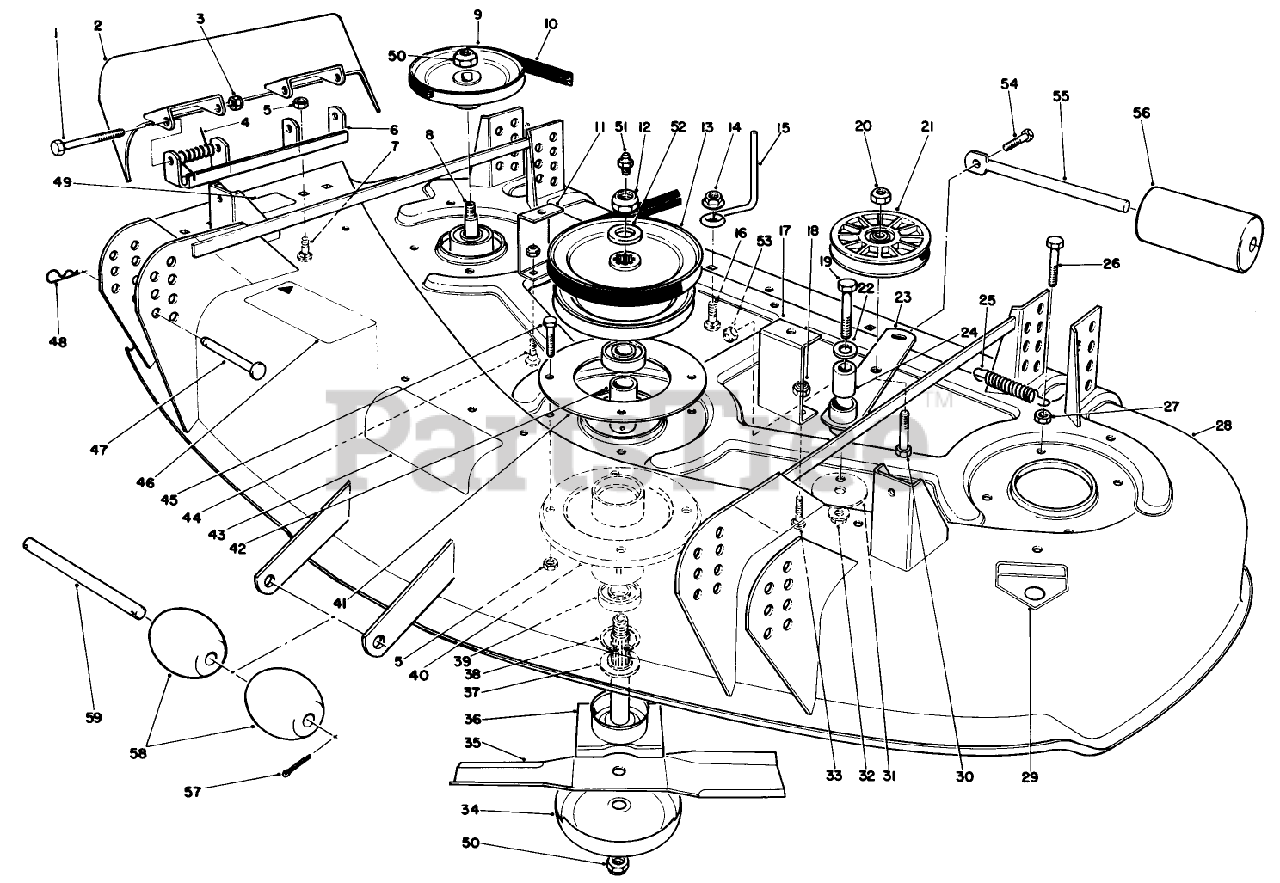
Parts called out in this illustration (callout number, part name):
1	SCREW-HH
3	NUT-HEX
4	SPRING
5	NUT-LOCK, CONE
6	PIVOT BRKT WA
7	SCREW-CARR
10	V-BELT
12	NUT-LOCK, NI
14	NUT-HF
15	ROD-BELT
16	BOLT-CARR
18	NUT-LOCK, NI
19	SCREW-HH
20	NUT-HEX
22	WASHER-FLAT
24	SLEEVE
25	SPRING-EXTENSION
26	SCREW-HH
27	NUT-JAM
29	DECAL-DANGER
30	SCREW-HH
31	WASHER-END
32	NUT-HF
33	SCREW-CARR
36	SPDL/BLD RET.WA
37	IDLER SPACER
39	BEARING-BALL
44	BOLT-CARR
45	SCREW-HH
47	PIN-CLEVIS
48	PIN-HAIR
49	CAUTION DECAL (BLADE)
50	NUT-LOCK NI
51	FITTING-GREASE
52	WASHER
53	NUT-HEX
54	SCREW-HH
55	ROD-ROLLER
56	ROLLER-DECK
58	ROLLER
59	SHAFT-ROLLER
